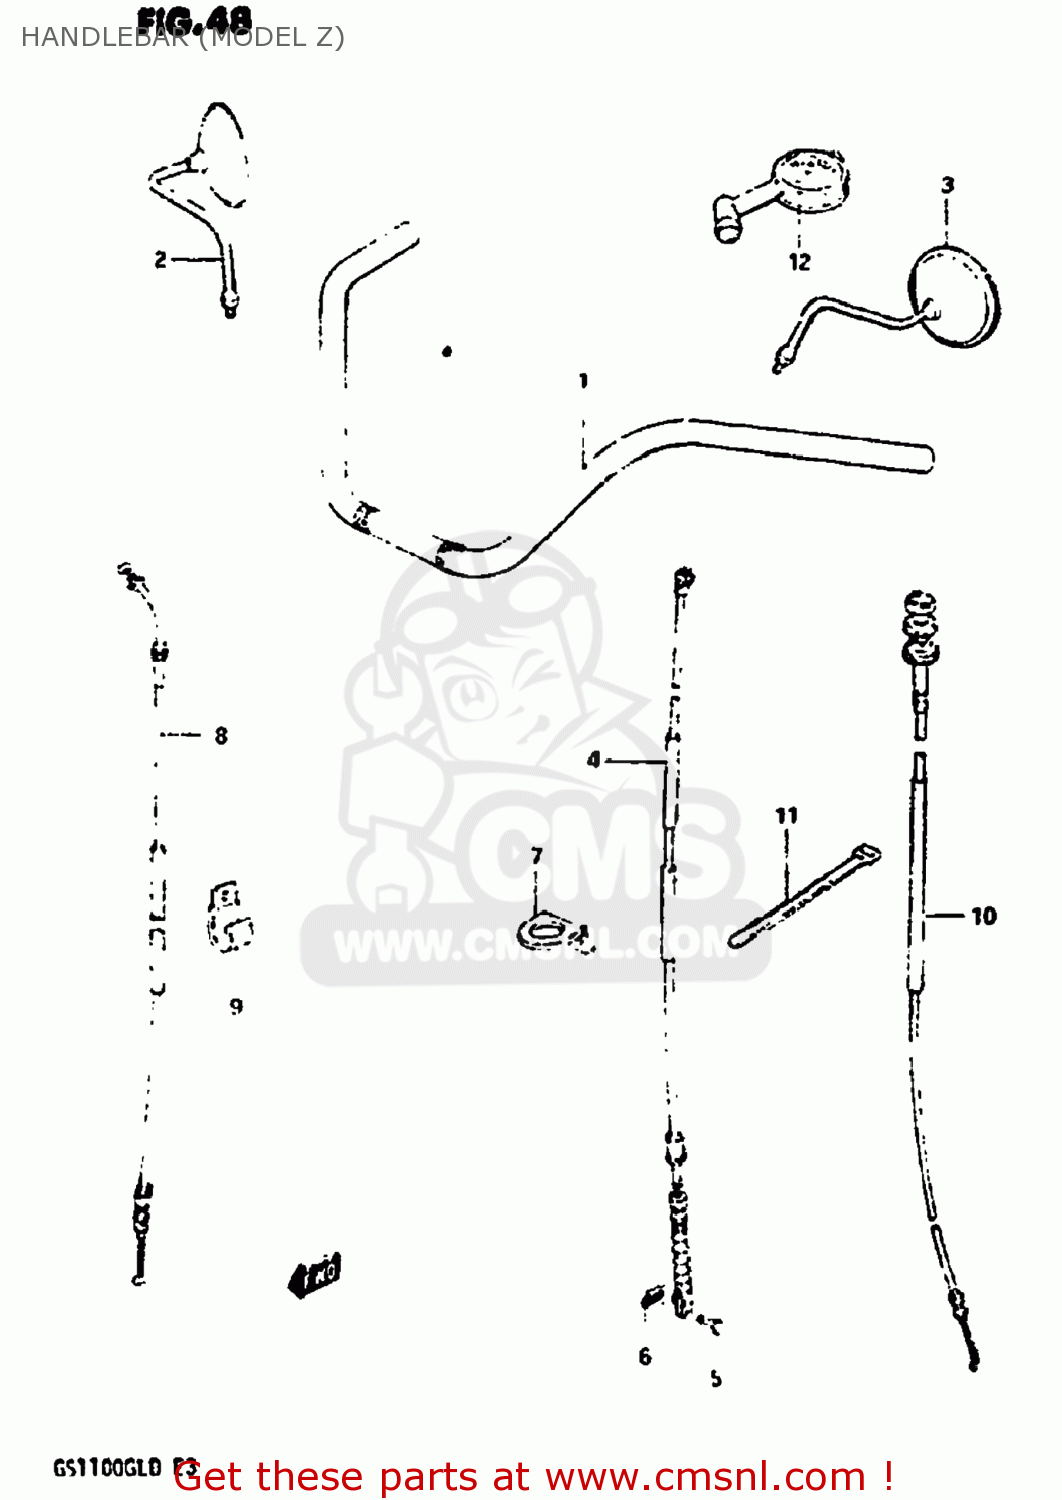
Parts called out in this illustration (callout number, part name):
1	HANDLEBAR
2	MIRROR ASSEMBLY,RIGHT
3	MIRROR ASSEMBLY,LEFT
4	CABLE ASSY,CLUTCH
5	PIN(L:15)
6	PIN
7	GUIDE,BRAKE HOSE
8	CABLE ASSEMBLY,THROTTLE
9	CLAMP
10	CABLE ASSEMBLY,STARTER
11	CLAMP(L:120)
12	GAUGE ASSY,AIR PRESSURE
